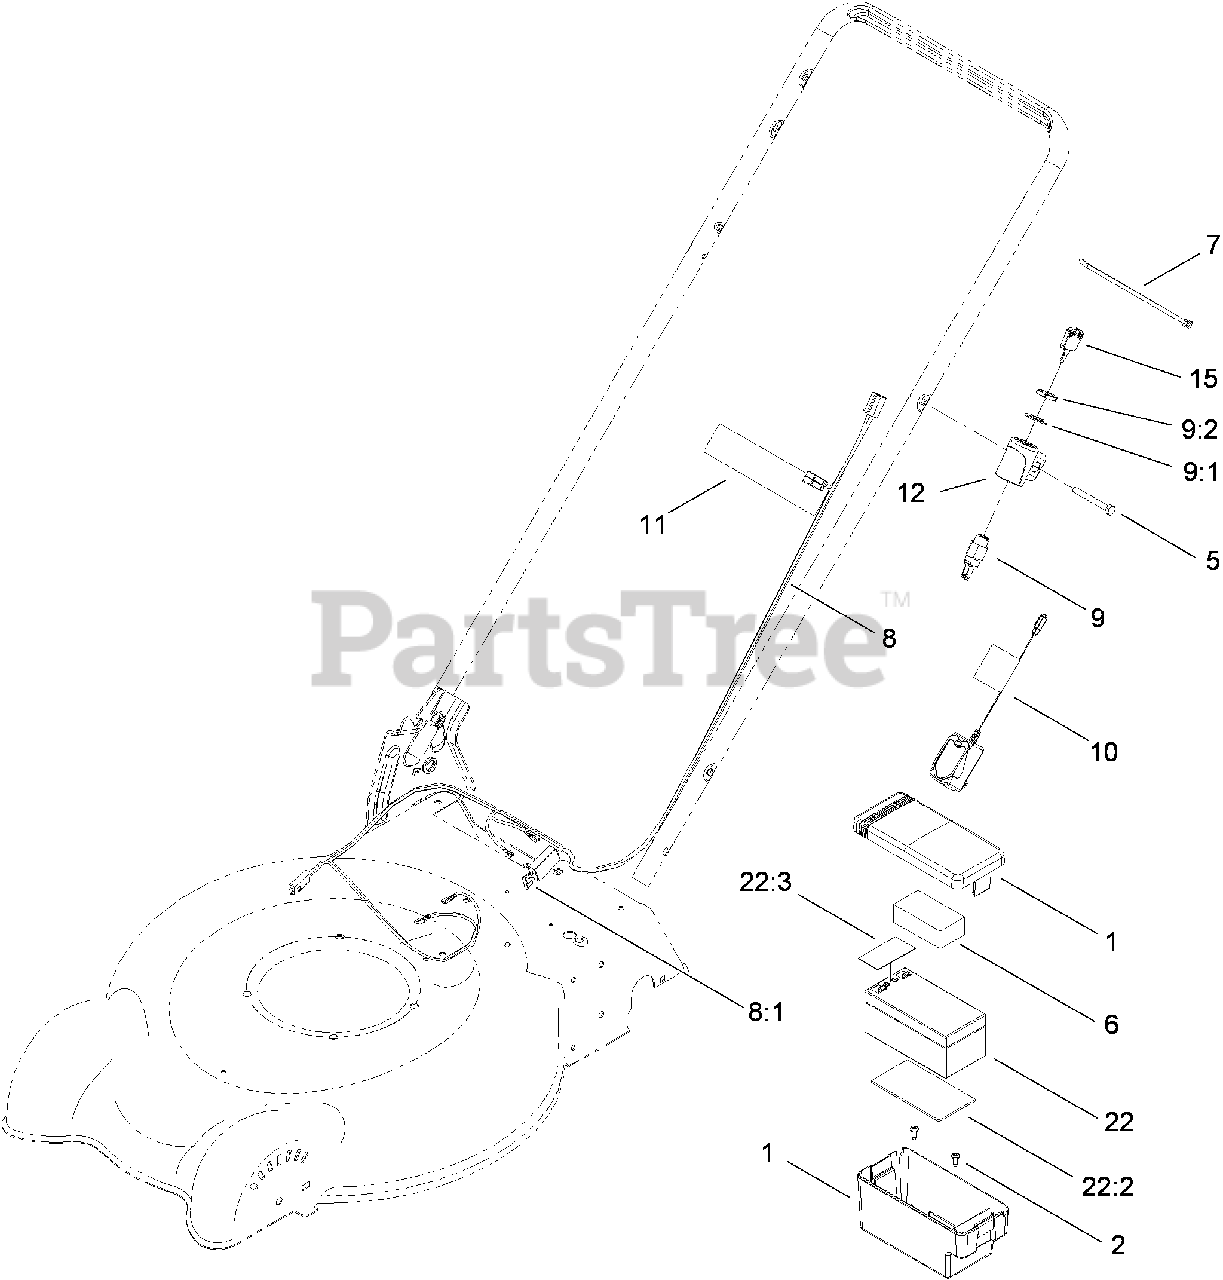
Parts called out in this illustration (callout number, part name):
1	BATTERY BOX ASM
2	SCREW-THREAD FORMING
5	SCREW-HH
6	FOAM-BATTERY, TOP
7	STRAP-TIE
8	HARNESS-WIRE
8:1	FUSE-40 AMP
9	STARTER SWITCH ASM
9:1	WASHER-TOOTH, INTERNAL
10	CHARGER-BATTERY
11	DECAL-HARNESS
12	MOUNT-SWITCH
22:2	FOAM-BATTERY
22:3	DECAL-TERMINAL, BATTERY
